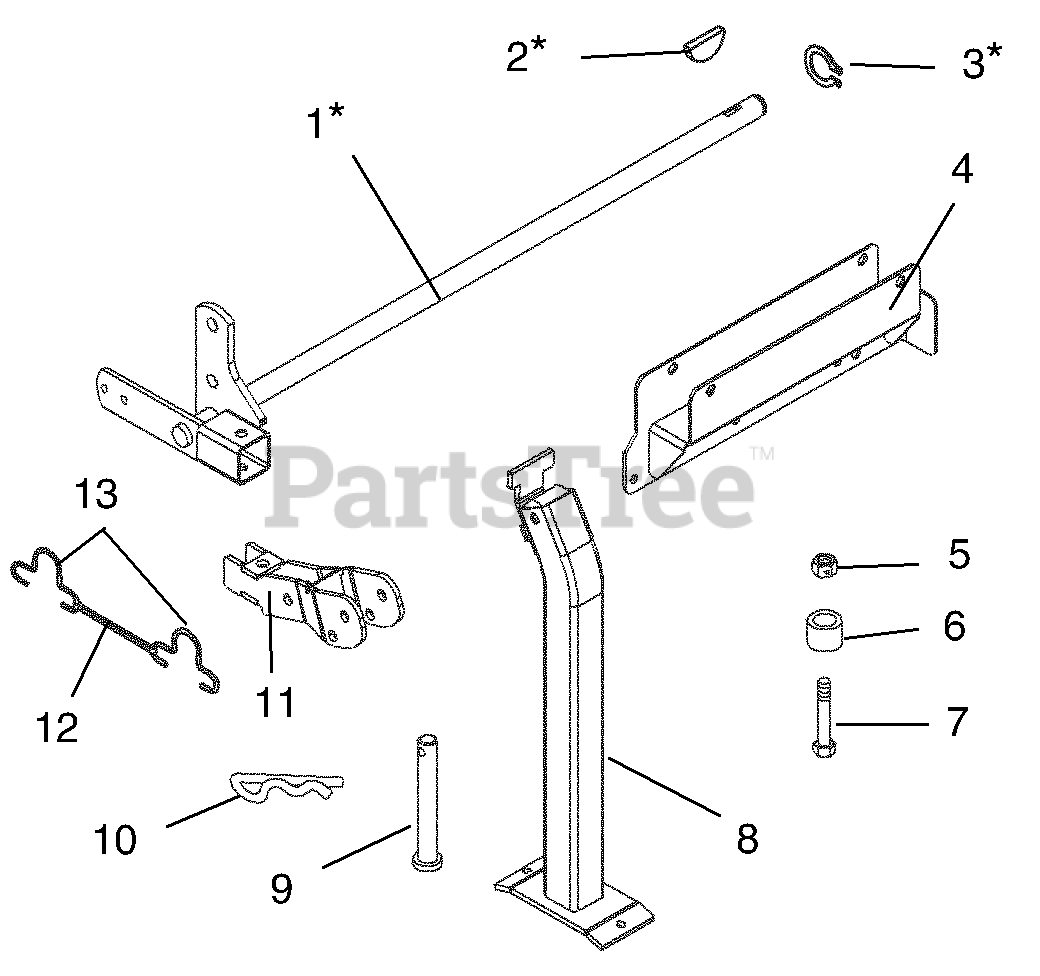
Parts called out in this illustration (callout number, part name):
1	WMT, LIFT ARM
2	KEY-WDRF .25X1.00 HRD #15
3	RG-RTNG-EXT 1.00X.078
4	WMT, LIFT TRANSPORT
5	@NUT-LK-TOP-FLG .38-16 YWZC
6	SPACER .390X1.000X.562
7	@BLT-HEX .38-16X1.75 GR5 YWZC
8	WMT, FOOT
9	PIN, CLEVIS .50 X 3.00 YWZC
10	PIN-HAIR-INT .15X2.937 YWZC
11	WMT, CONNECTOR
12	BATTERY STRAP
